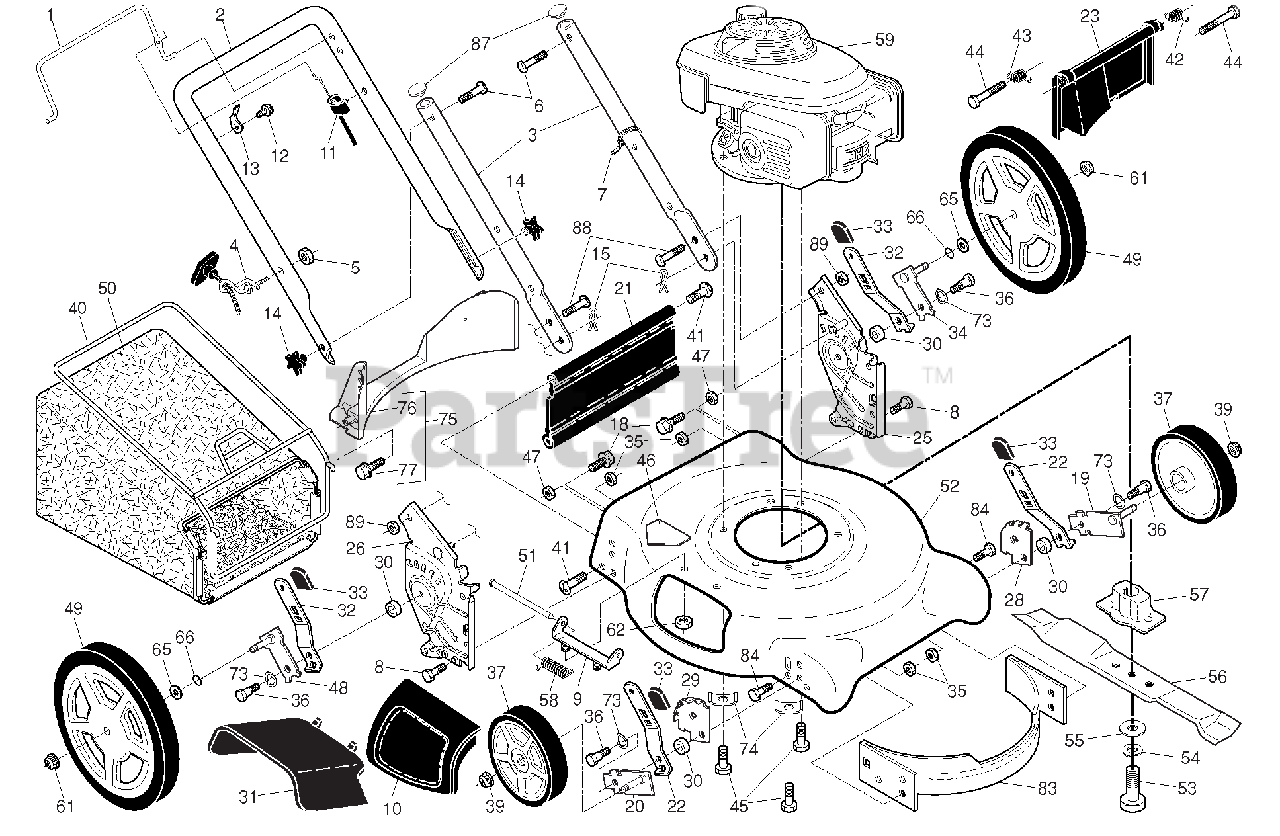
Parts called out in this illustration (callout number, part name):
1	CONTROL BAR
2	UPPER HANDLE
3	BAR, LOWER HANDLE
4	Rope Guide
5	Nut, Hex
6	Handle Bolt
7	Wire Tie
8	Bolt, Hex Head 5/16-18 x 3/4
9	Hinge Bracket
10	Mulcher Door
11	ENGINE ZONE CONTROL CABLE
12	SCREW, HEX WASHER HEAD
13	UP-STOP BRACKET
14	Handle Knob
15	Hairpin Cotter
18	SCREW.HEX.WASHEAD.1/4-20 X 3/8
19	Axle Arm Assembly, Front, LH
20	Axle Arm Assembly, Front, RH
21	Kit, Rear Skirt
22	Selector Spring, Front
23	Rear Door Assembly
25	HANDLE BRACKET ASSEMBLY, LH
26	HANDLE BRACKET ASSEMBLY, RH
28	Wheel Adjusting Bracket, LH
29	Wheel Adjusting Bracket, RH
31	Discharge Deflector
32	SELECTOR SPRING, REAR
33	Selector Knob
34	Axle Arm Assembly, Rear, LH
35	Locknut, Hex 5/16-18
36	Shoulder Bolt
37	WHEEL & TIRE ASSEMBLY, FRONT
39	Nut, Hex
40	Frame, Grassbag
41	HINGE SCREW
42	Spring, Rear Door, LH
43	Spring, Rear Door, RH
44	Bolt, Rear Door
45	Screw, Hex Head, Threaded, Rol
46	Danger Decal
47	Nut, Hex
48	Axle Arm Assembly, Rear, RH
49	WHEEL & TIRE ASSEMBLY, REAR
50	Grassbag
51	Hinge Rod
52	KIT, LAWN MOWER HOUSING
53	Screw, Hex Head, Grade 8 3/8-2
54	Helical Lockwasher
55	Hardened Washer
56	21" Blade
57	BLADE ADAPTER
58	Hinge Spring
61	Flanged Locknut, Hex
62	Locknut, Hex 1/4-20
65	Washer, Flat
73	Washer, Curved, Cylindrical
74	Washer, Special, Engine
75	Kit, Rear Baffle (Includes 3 S
76	Baffle, Rear
77	Screw, Rear Baffle
83	BAFFLE, FRONT
84	BOLT.5/16-18HEX.WHS.HD.LCKSERR
87	PLUG, HANDLE BAR
88	BOLT, CARRIAGE 5/16-18 X 5/8
89	Nut, Hex, Flangelock
